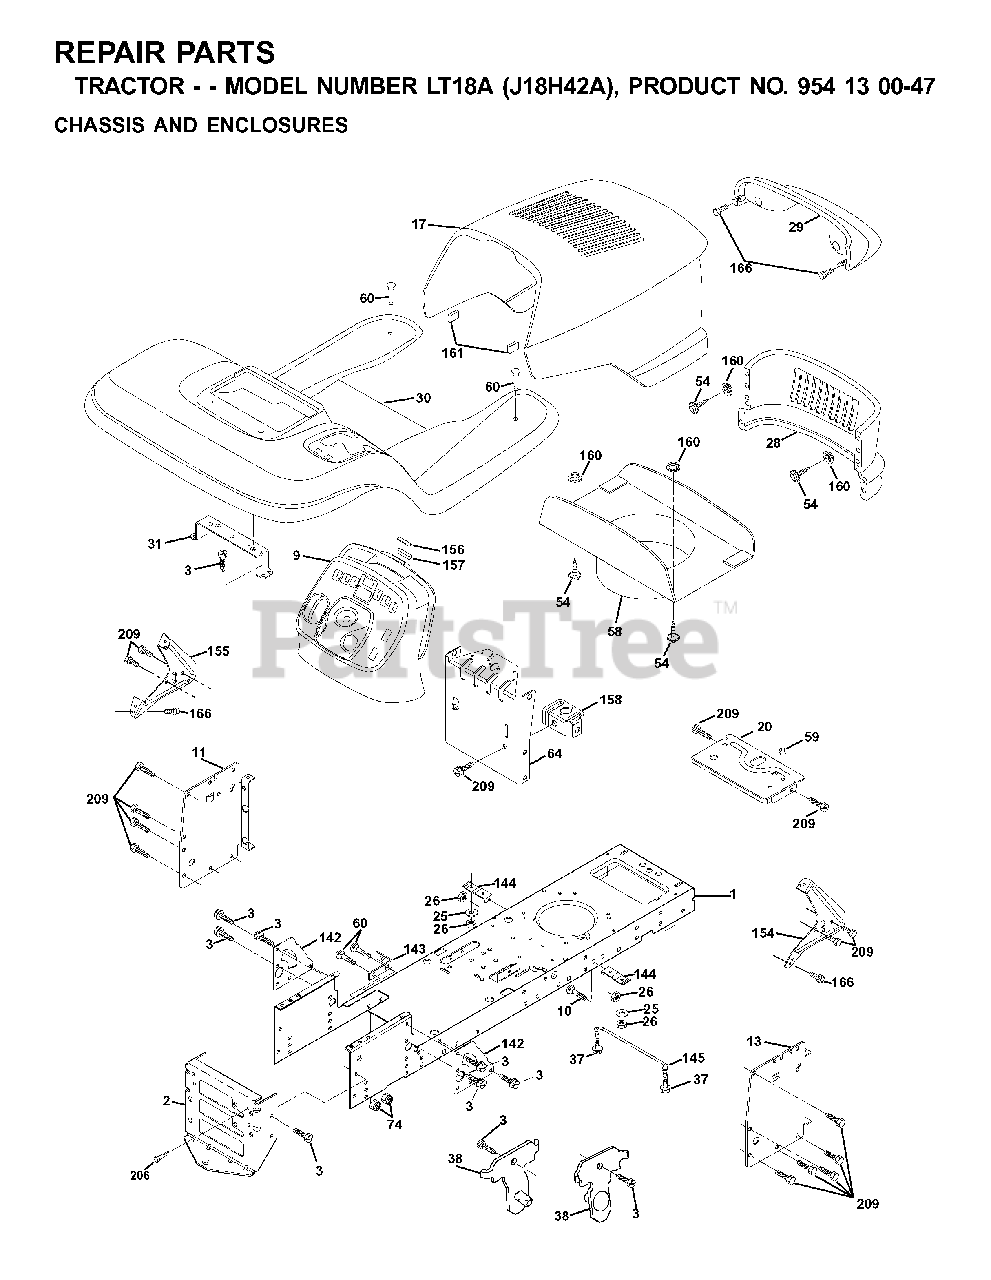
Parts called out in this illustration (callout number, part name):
2	DRAWBAR
3	SCREW 3/8-16X3/4
10	BOLT D
25	WASHER
26	NUT
38	BRACKET
59	SNAP BUSHING T
74	LOCKNUT
142	PLATE
143	BRACKET, SWAY BAR
144	BRACKET FOOTREST
145	ROD PIVOT CHASSIS/HOOD
161	EXTRUSION BUMPER
166	SCREW
206	SHOULDER BOLT 5/16-18TT
209	SCREW, 3/8-16X3/4
